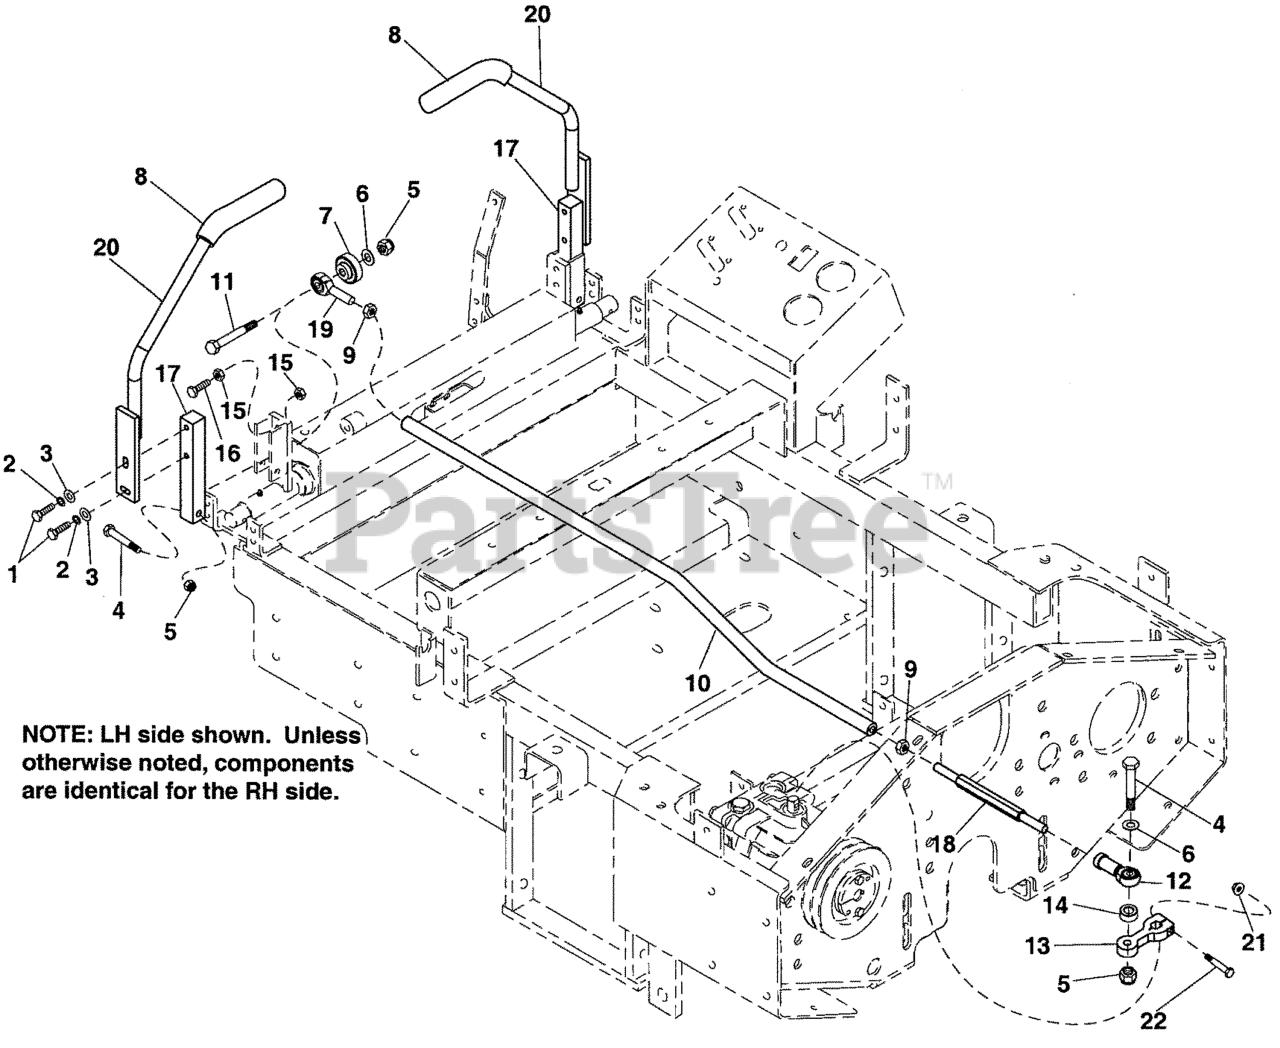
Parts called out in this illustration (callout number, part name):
1	BOLT, 5/16-18 X 3/4 GD5
2	WASHER, 5/16 LOCK CZ
3	WASHER, 5/16" SAE
4	BOLT, 3/8-16 X 2, GD5, CZ
5	NUT, 3/8-16 HEX NYLON LOCK
6	WASHER, 3/8 SAE
7	BEARING & INSERT ASSEMBLY
7	BEARING, BALL 11/16X1-9/16X15/32
7	Insert
8	FOAM GRIP
9	NUT, Hex, 3/8-24
10	CONTROL ROD
11	BOLT, 3/8-16 X 2-1/4" GD5 CZ
12	BALL JOINT, 3/8 L.H., Female
13	CONTROL ARM
14	SPACER
15	NUT, 5/16-18 HEX
16	BOLT, 5/16-18 X 1 GD5 YZ
17	CONTROL HANDLE BASE
18	ADJUSTABLE LINK
19	BALL JOINT, 3/8
20	MOTION CONTROL LEVER
21	NUT, 1/4-20 HEX SERR. FLANGE
22	BOLT, 1/4-20 x 1-3/4
